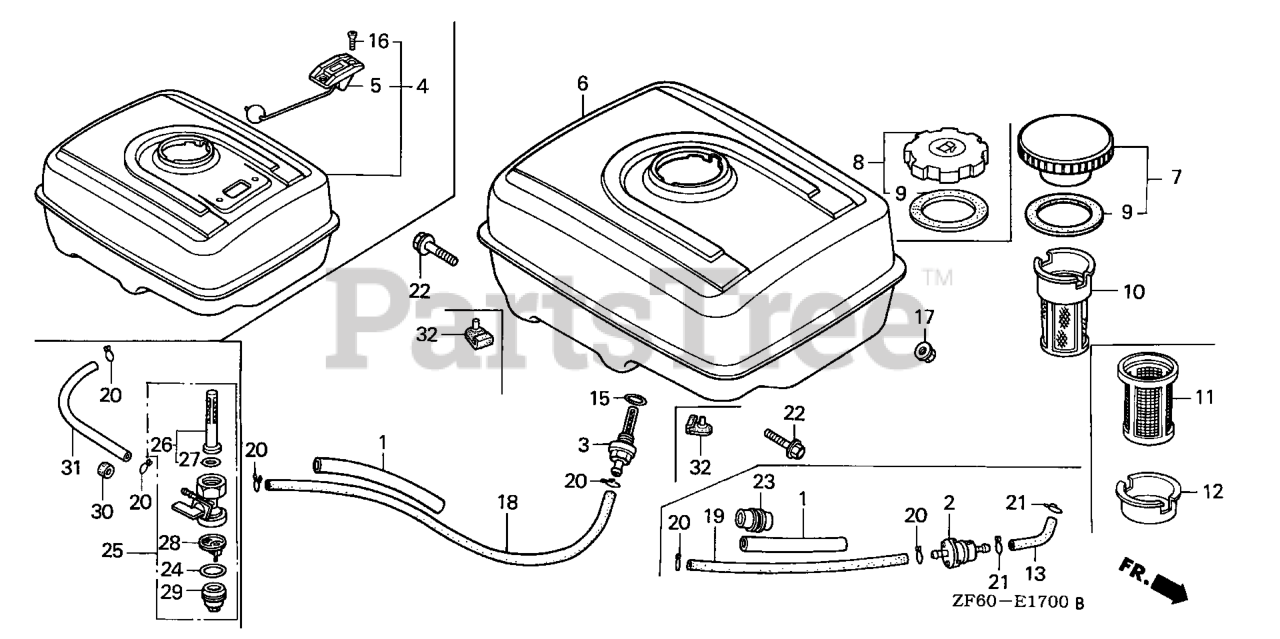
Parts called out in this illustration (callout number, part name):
1	RUBBER, SUPPORTER (107MM)
3	JOINT, FUEL TANK
6	TANK, FUEL *NH31* (MCKINLEY WHITE)
6	TANK, FUEL *NH1* (BLACK)
8	CAP, FUEL FILLER (BLACK) Use up to Engine SN 2115700.
8	CAP, FUEL FILLER (CHROME PLATED)
8	CAP COMP
9	GASKET, FUEL FILLER CAP (39X58X3) (NOT AVAILABLE)
9	GASKET, FUEL FILLER CAP Use from Engine SN 1543258.
9	GASKET, FUEL FILLER CAP (39X58X3)
10	FILTER, FUEL
15	O-RING (14MM) (ARAI) Use up to Engine SN 2949254.
17	NUT, FLANGE (8MM)
18	BULK HOSE, FUEL (4.5X3000) (Honda Code 5137104). (4.5X140)
20	CLIP, TUBE (B8)
22	BOLT, FLANGE (8X25)
